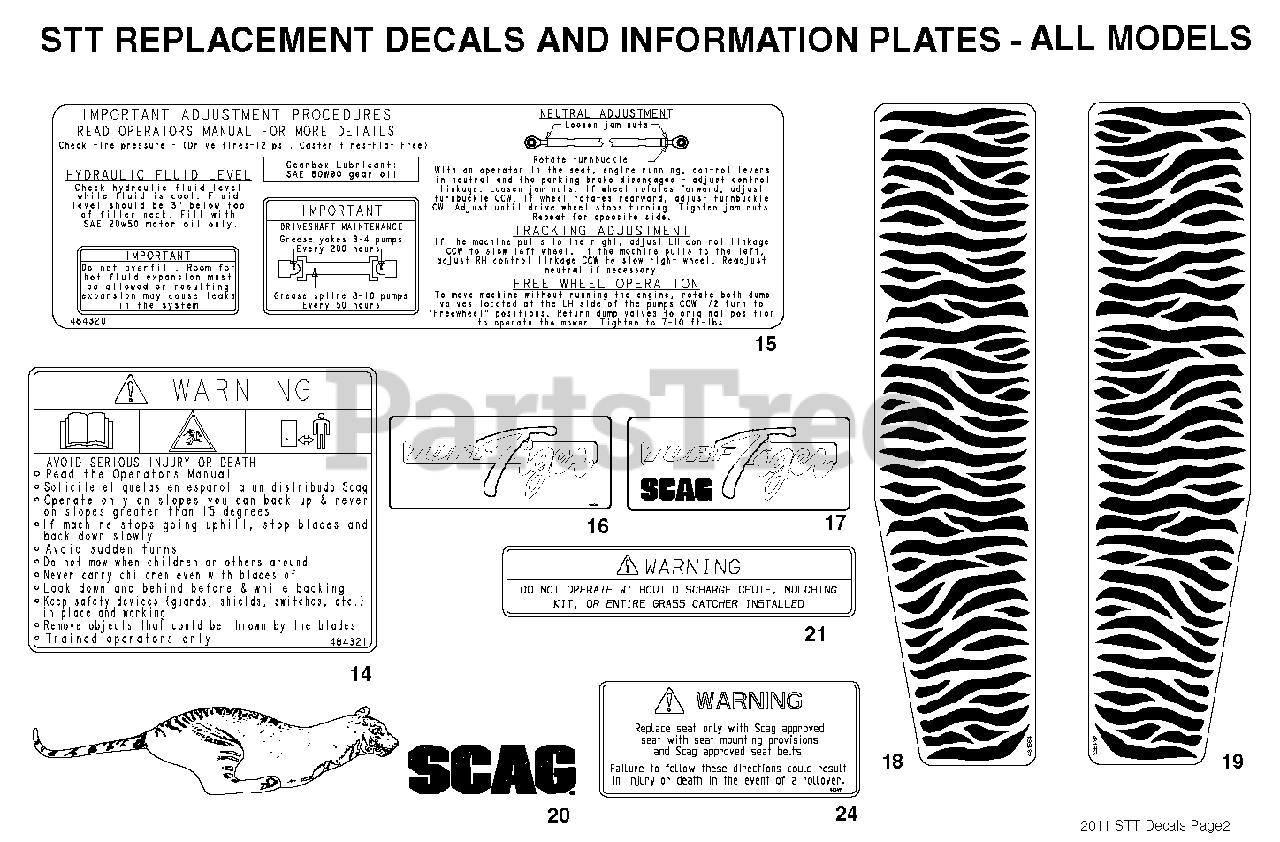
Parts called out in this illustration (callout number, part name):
14	Decal, Fuel Tank Warning
15	Decal, STT Adjustments
16	Decal, Turf Tiger
17	Decal, Turf Tiger
18	Decal, Stripes-RH
19	Decal, Stripes-LH
20	Decal, Tiger
21	Decal, Warning
24	Decal, ROPS
